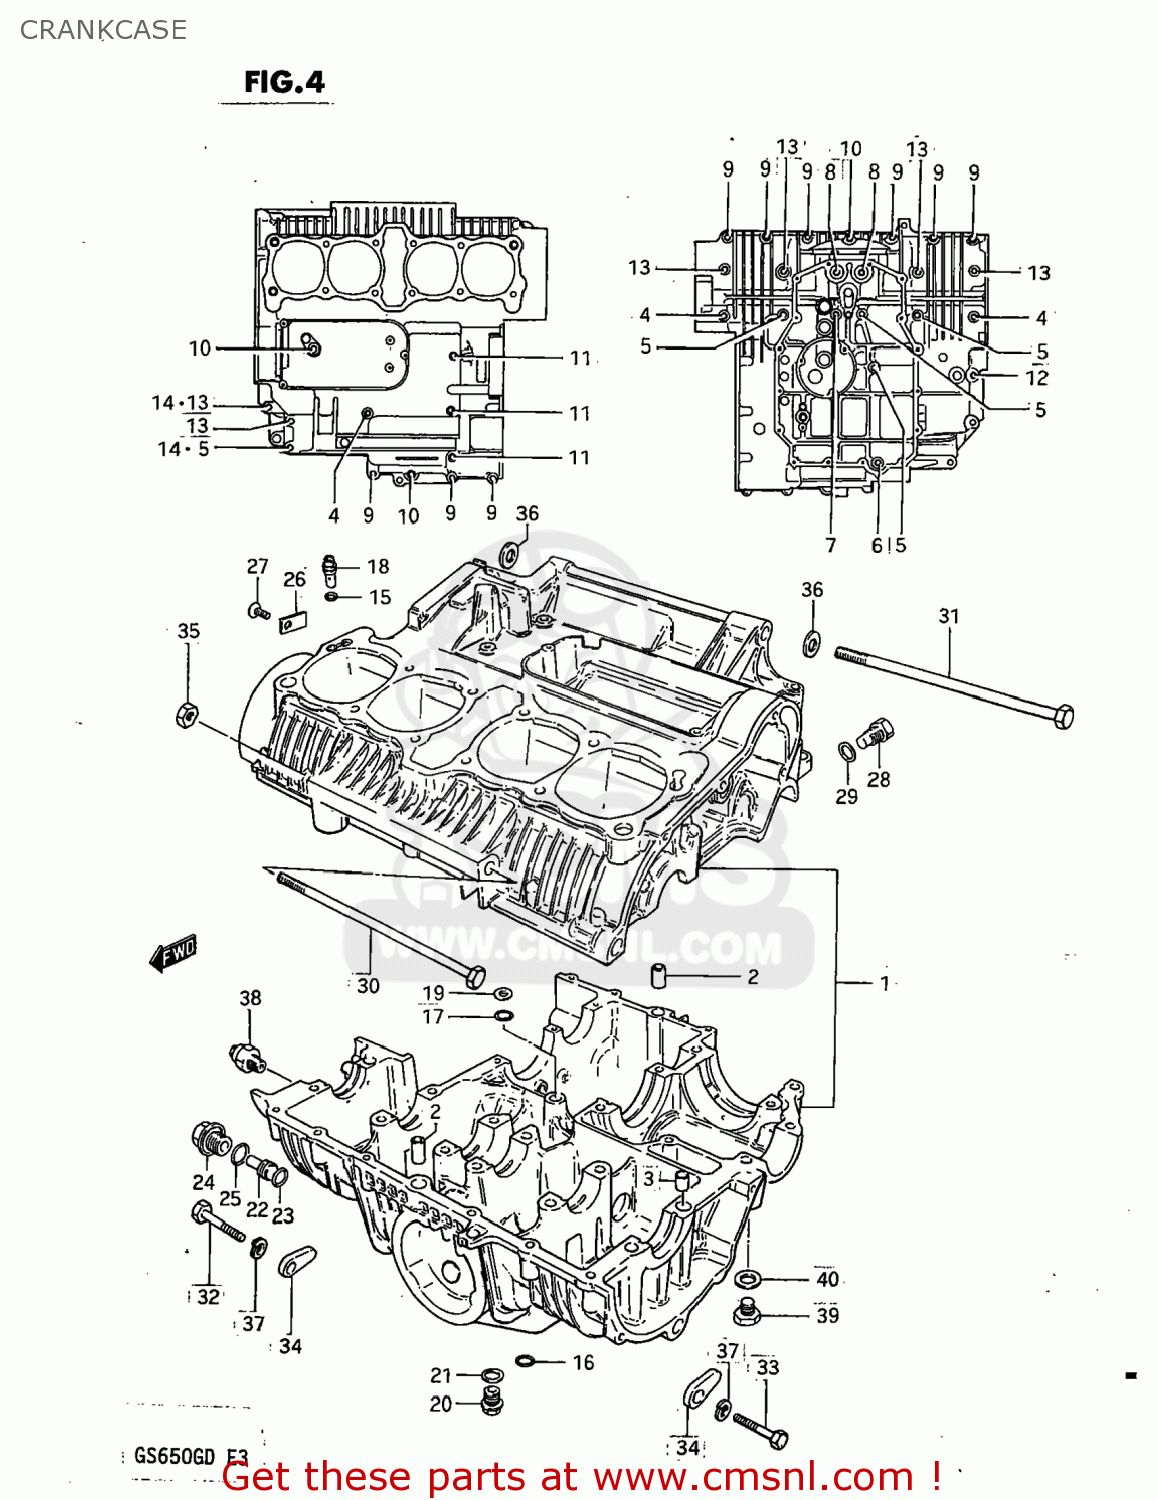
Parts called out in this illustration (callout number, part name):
1	CRANKCASE SET
2	PIN (11X20)(SUS)
3	PIN(10.4X13X22)
4	BOLT
5	BOLT
6	BOLT(8X135)
7	BOLT(8X140)
8	BOLT
9	BOLT
10	BOLT
11	BOLT (6X90)
12	BOLT (8X70)
13	BOLT (8X95)
14	NUT 8MM
15	O-RING,OIL GALLERY JET
16	O-RING
17	O RING(D:3.2,ID:12.9)
18	JET(12)
19	WASHER
20	PLUG
21	GASKET(16X22X2) (NAS)
22	PIN,OIL GALLERY
23	SEAL (D:1.9 ID:9.8)
24	PLUG
25	O RING(D:2.4,ID:17.8)
26	PLATE,OIL GALLERY PLUG
27	SCREW
28	PLUG
29	GASKET(12.1X16.2X3.7) (NAS)
30	BOLT
31	BOLT 10X250
32	BOLT 10X55
33	BOLT 10X40
34	NUT
35	NUT 10MM
36	WASHER
37	LOCK WASHER
38	SWITCH ASSEMBLY
39	PLUG
40	GASKET(14X19.2X2) (NAS)
